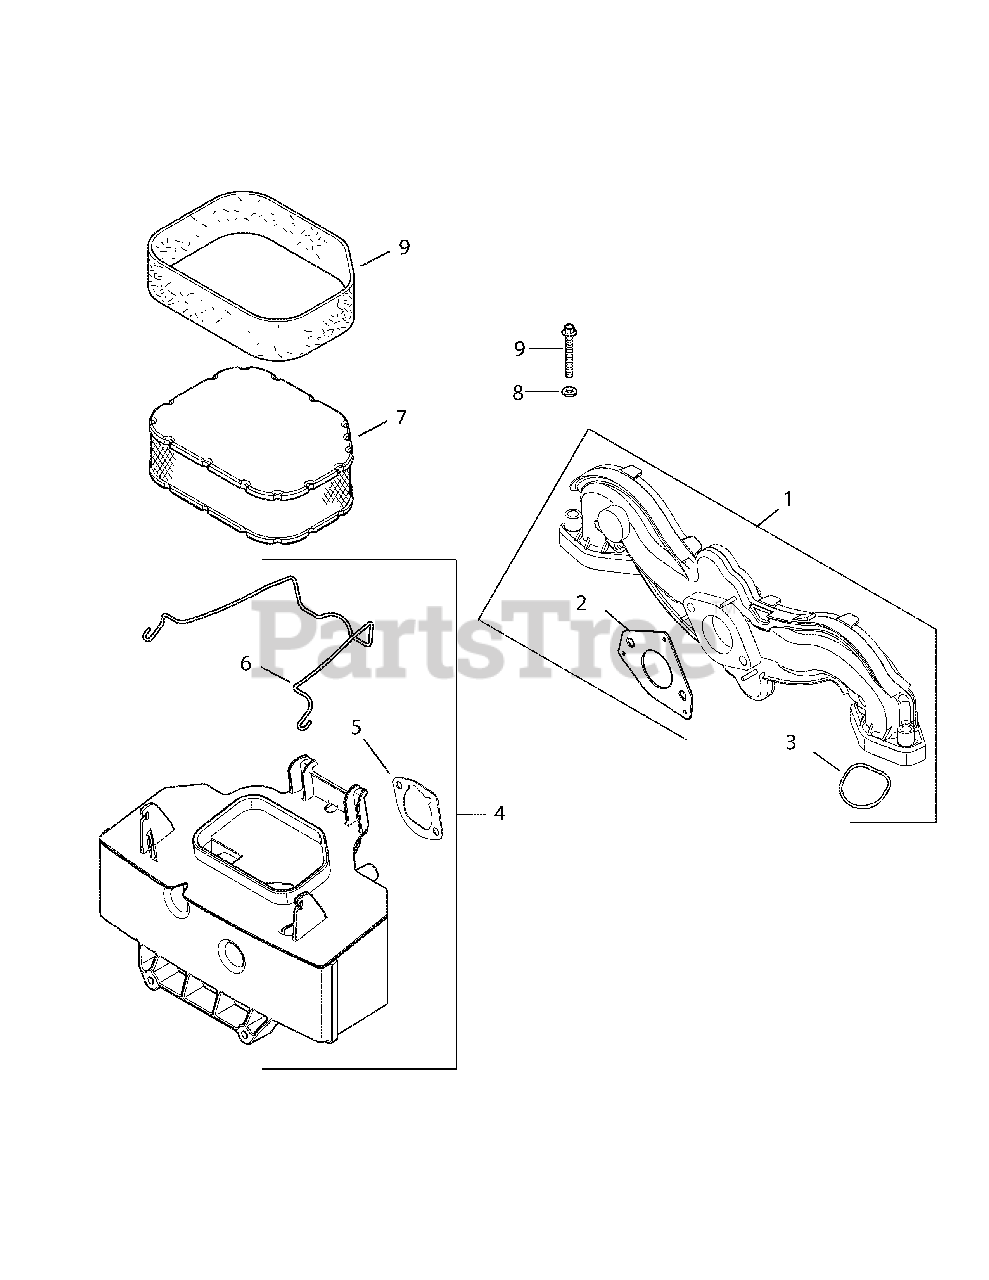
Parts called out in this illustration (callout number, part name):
1	Manifold, intake (Includes 2,3)
2	Gasket, carburetor
3	O-Ring, intake port
4	Base, air cleaner (Includes 5,6)
5	Gasket, air cleaner base
6	Latch, air cleaner element
7	Element, air cleaner
8	Washer, Flat, 1/4
8	Screw, hex. flange M6x1.0x40
9	Pre-cleaner, element
